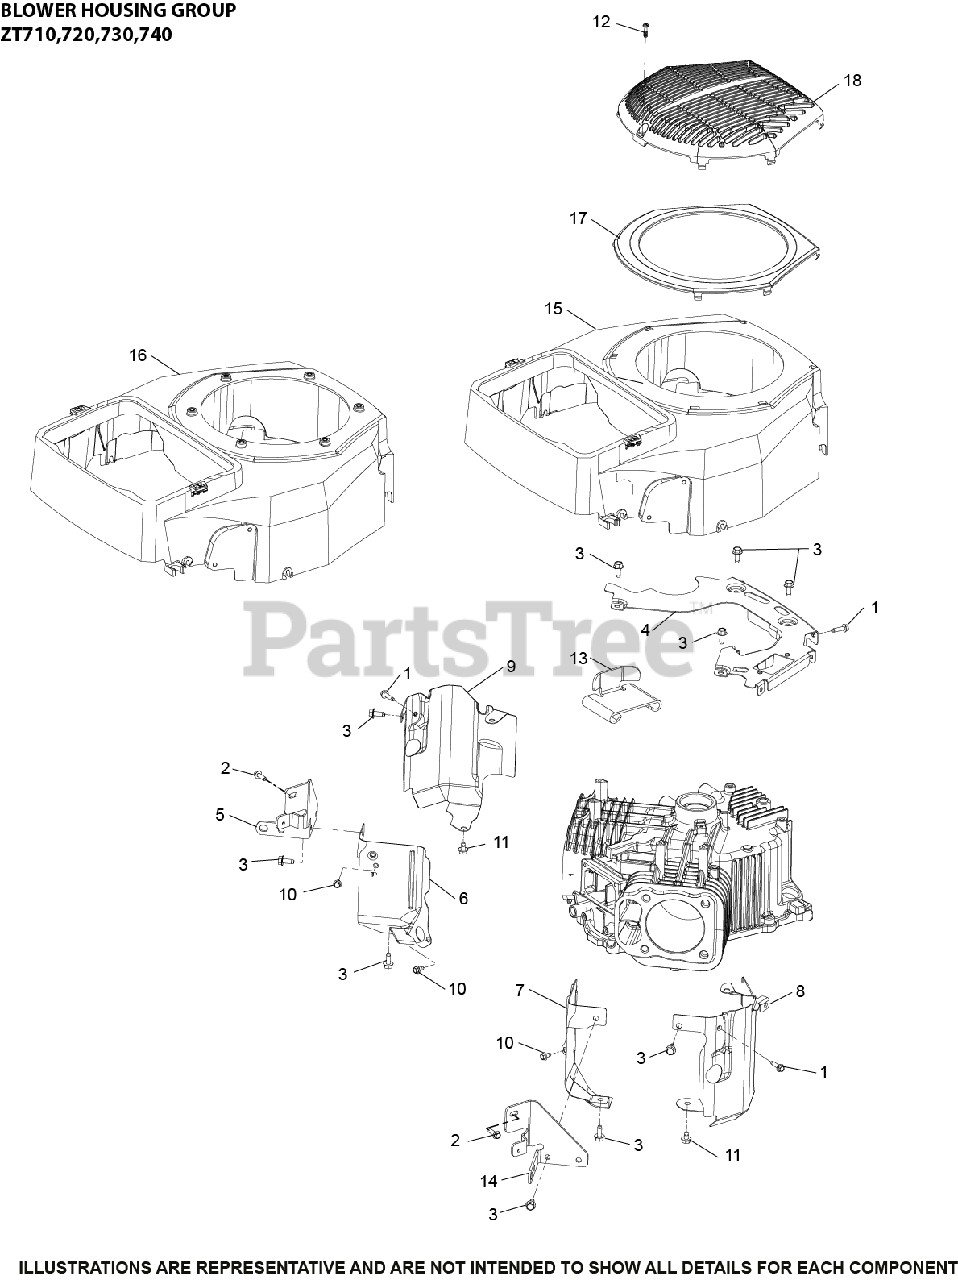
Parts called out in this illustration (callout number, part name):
1	SCREW, THREAD FORMING - USE 25 086 473-S
2	SCREW, HI-LOW
3	SCREW, THREAD FORMING
4	PLATE, BACKING
5	BRACKET, AIR CLEANER BASE (#1 SIDE)
6	VALLEY, BAFFLE #1
7	BAFFLE, VALLEY #2 USE 32 063 21-S
8	BAFFLE, LEFT BARREL
9	BAFFLE, RIGHT BARREL
10	SCREW, THREAD FORMING
14	BRACKET, AIR CLEANER BASE (#2 SIDE)
16	HOUSING, BLOWER ASSEMBLY USE 16 027 07-S
